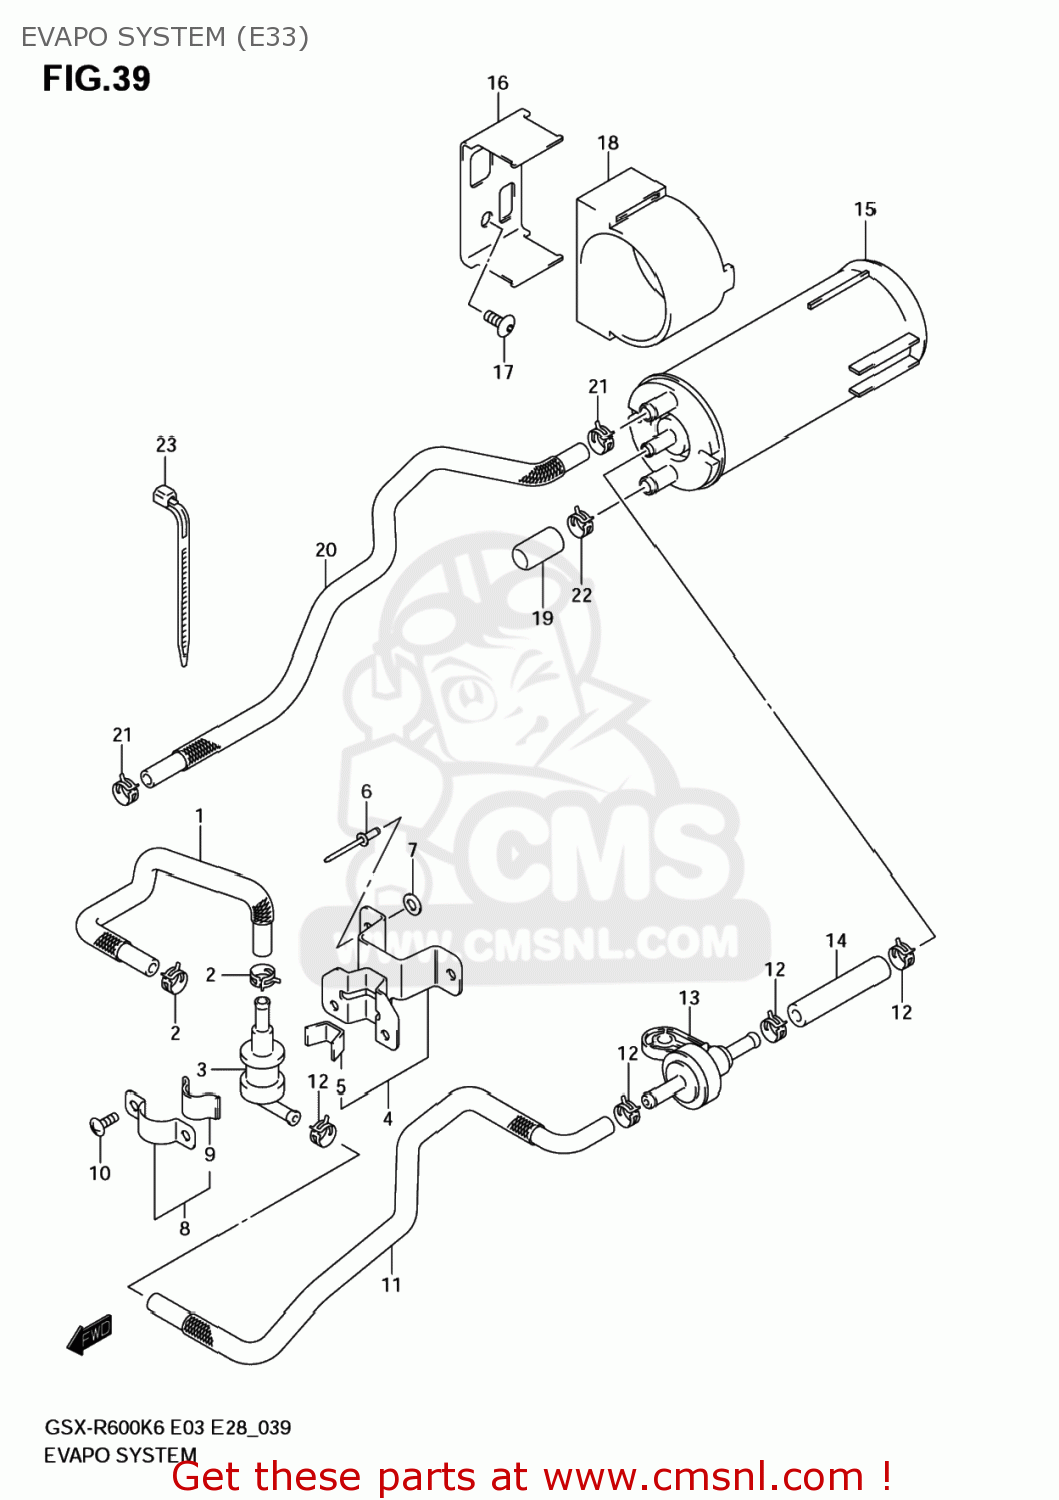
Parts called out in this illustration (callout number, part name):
1	HOSE,TANK & BREATHER VALVE
2	CLIP
3	VALVE,FUEL TANK BREATHER
4	PLATE,BREATHER VALVE
5	CUSHION
6	RIVET
7	WASHER
8	PLATE,FUEL TANK BREATHER NO.2
9	CUSHION
10	SCREW
11	HOSE,BRTHR VALVE & 2 WAY VALVE
12	CLIP
13	VALVE,2 WAY & BREATHER VALVE
14	HOSE(5.4X11.4X600)
15	CANISTER
16	BRACKET,CANISTER
17	SCREW,6X10
18	CUSHION,CANISTER
19	CAP,OD:11.5
20	HOSE,CSTR PURGE
21	CLIP,RR RSVR T
22	CLIP
23	CLAMP(L:125)
